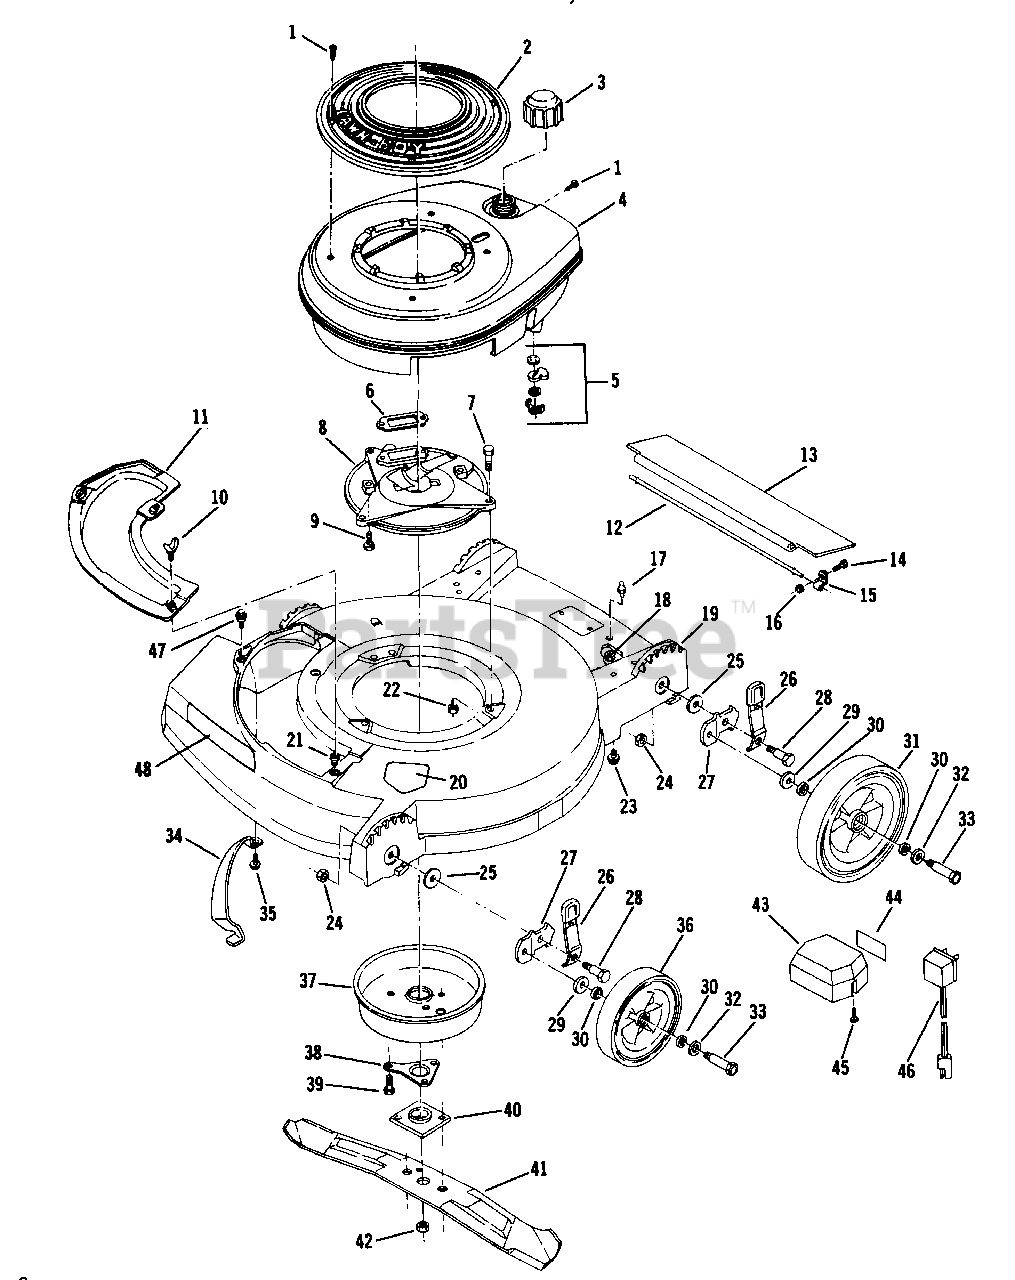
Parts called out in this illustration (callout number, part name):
1	Screw
2	Cover-Shroud
3	Fuel Cap
4	Shroud
5	Fuel Shut-Off Assembly
6	Gasket-Exhaust
7	Screw-Muffler Plate to Housing
8	Plate-Muffler
9	Screw-Muffler Plate to Block
10	Wing Screw
11	Cover Plate
12	Rod-Trailing Shield
13	Shield-Trailing
14	Screw
17	Ball Stud-Batt. Mtg.
18	Nut-Ball Stud
19	Housing
20	Decal-Blade Contact Warning
21	Grommet
22	Nut-Muffler Plate to Housing
26	Knob and Spring Assembly
27	Bracket
28	Bolt-Shoulder
30	Washer-Felt
31	Wheel-Rear
33	Bolt-Wheel
34	Toe Bar
35	Screw
36	Wheel-Front
37	Muffler-Cover Assembly
38	Support-Crankshaft
39	Screw-Muffler to Muffler Plate
40	Collar and Plate Assembly
41	Blade-21"
42	Nut-Blade
43	Batt. Box and Batt. Pack Assembly
46	Battery Charger Assembly
47	Screw-Plate and Chute Mtg.
48	Decal-Electric Restart
